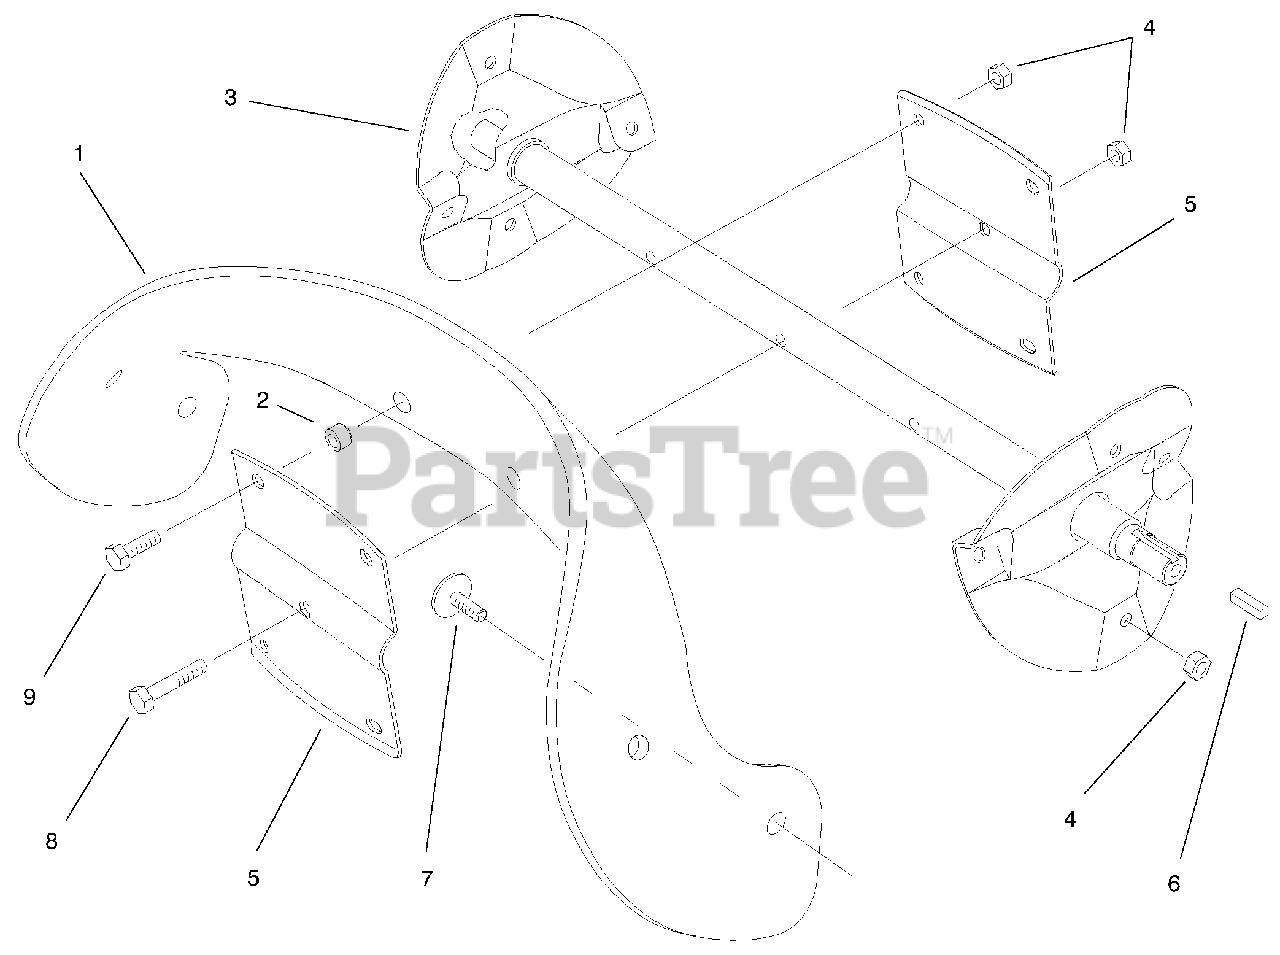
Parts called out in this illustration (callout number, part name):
1	Rotor Blade (Ccr 1000)
2	Rotor Bld Spacer
3	Rotor Wa
4	Nut-Lock Ni
5	Rotor Half
6	Key-Square
7	Screw-Csunk Oval
8	Screw-HH
9	Screw-HH
